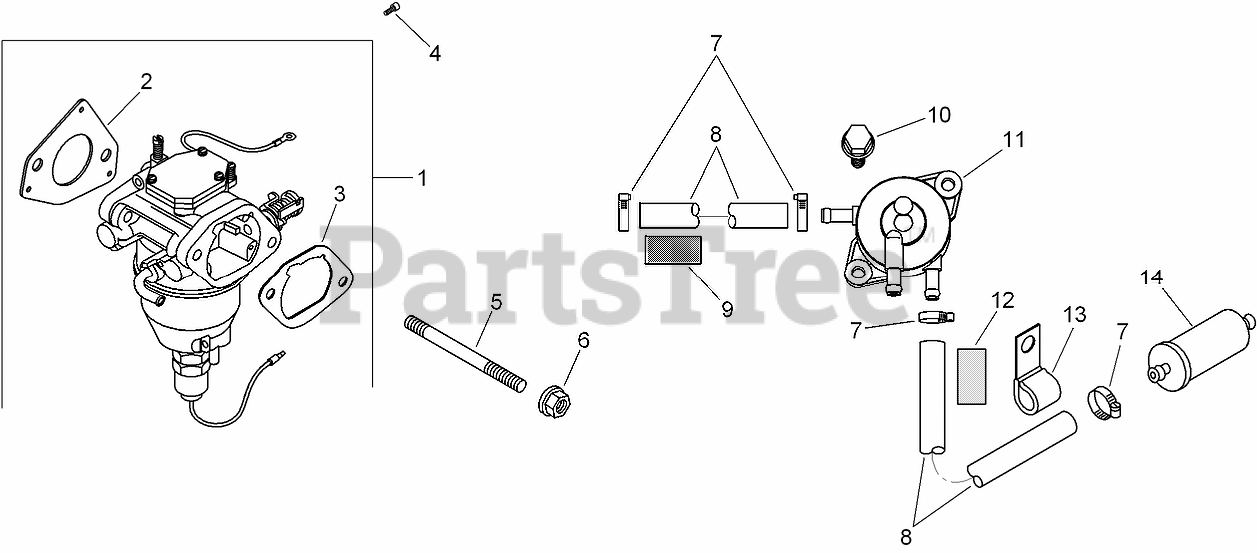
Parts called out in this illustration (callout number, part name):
1	CARBURETOR KIT-19mm KEIHIN (INCLUDES 2, 3)
2	GASKET-BASE, AIR CLEANER
3	GASKET-CARBURETOR
4	Screw-Stop, Throttle
5	STUD (M6X1.0X106)
6	NUT-FLANGE (M6X1.0)
7	CLAMP-HOSE, SPRING (1/2)
8	LINE-FUEL (24.0 CUT TO LENGTH)
9	SLEEVE-ABRASION, ANTI
10	SCREW-TAP (M6X1.7X18)
11	PUMP-FUEL
12	SLEEVE-ABRASION, ANTI
13	CLIP-CABLE
14	FILTER-FUEL
